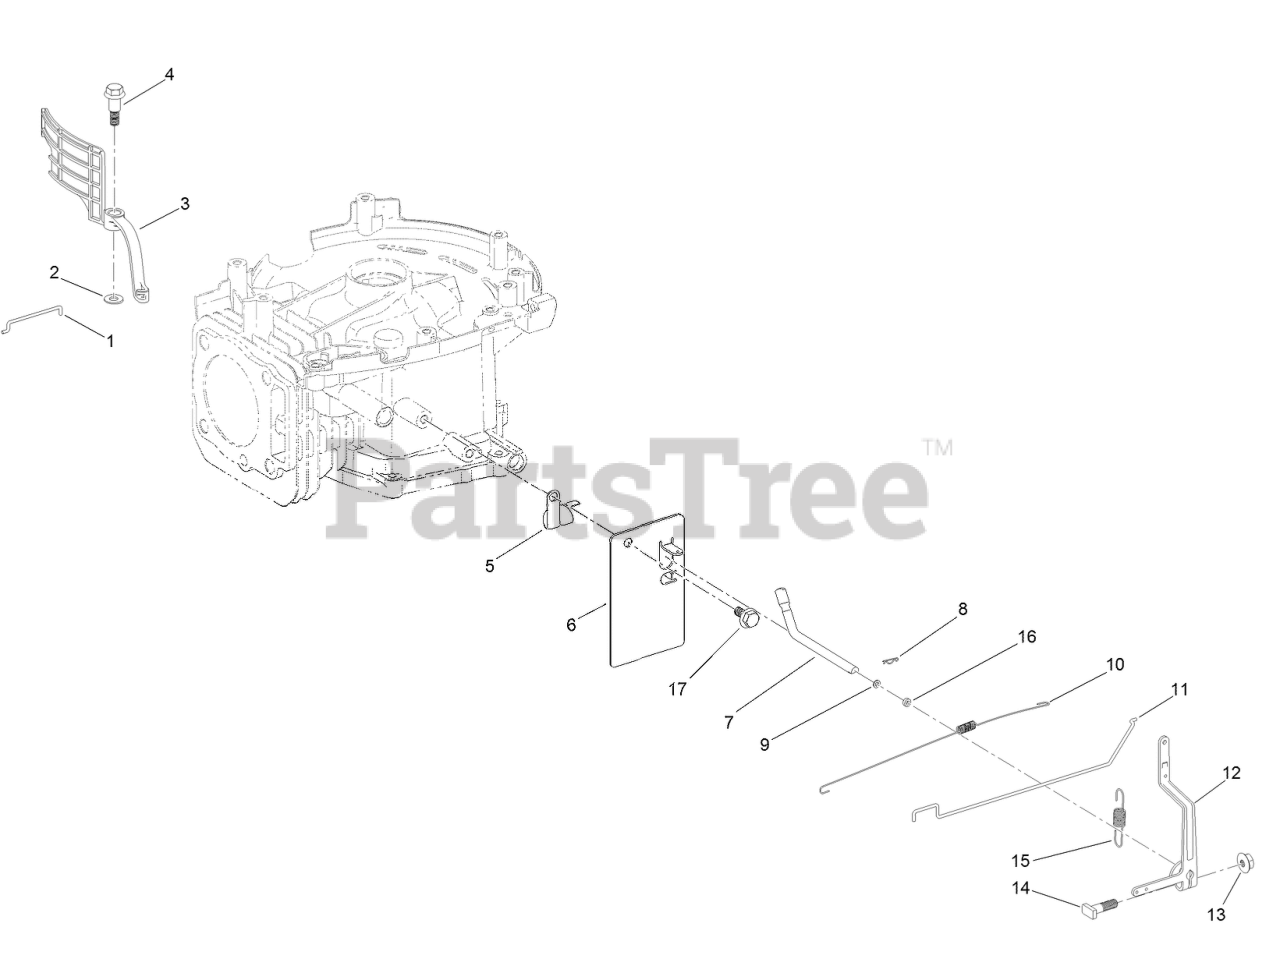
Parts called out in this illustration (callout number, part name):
1	LINKAGE-CHOKE
2	WASHER-PLAIN
3	AIR VANE-AUTOCHOKE
4	SCREW-SHOULDER, HWH
5	CLIP-HARNESS, WIRE
6	PLATE-CONTROL, THROTTLE
8	PIN-HAIR
10	SPRING-RETURN, THROTTLE
11	ROD-GOVERNOR
12	ARM-GOVERNOR
13	NUT-FLANGE
14	BOLT-ARM, GOVERNOR
15	SPRING-GOVERNOR
16	SEAL-OIL
17	SCREW-HHF
